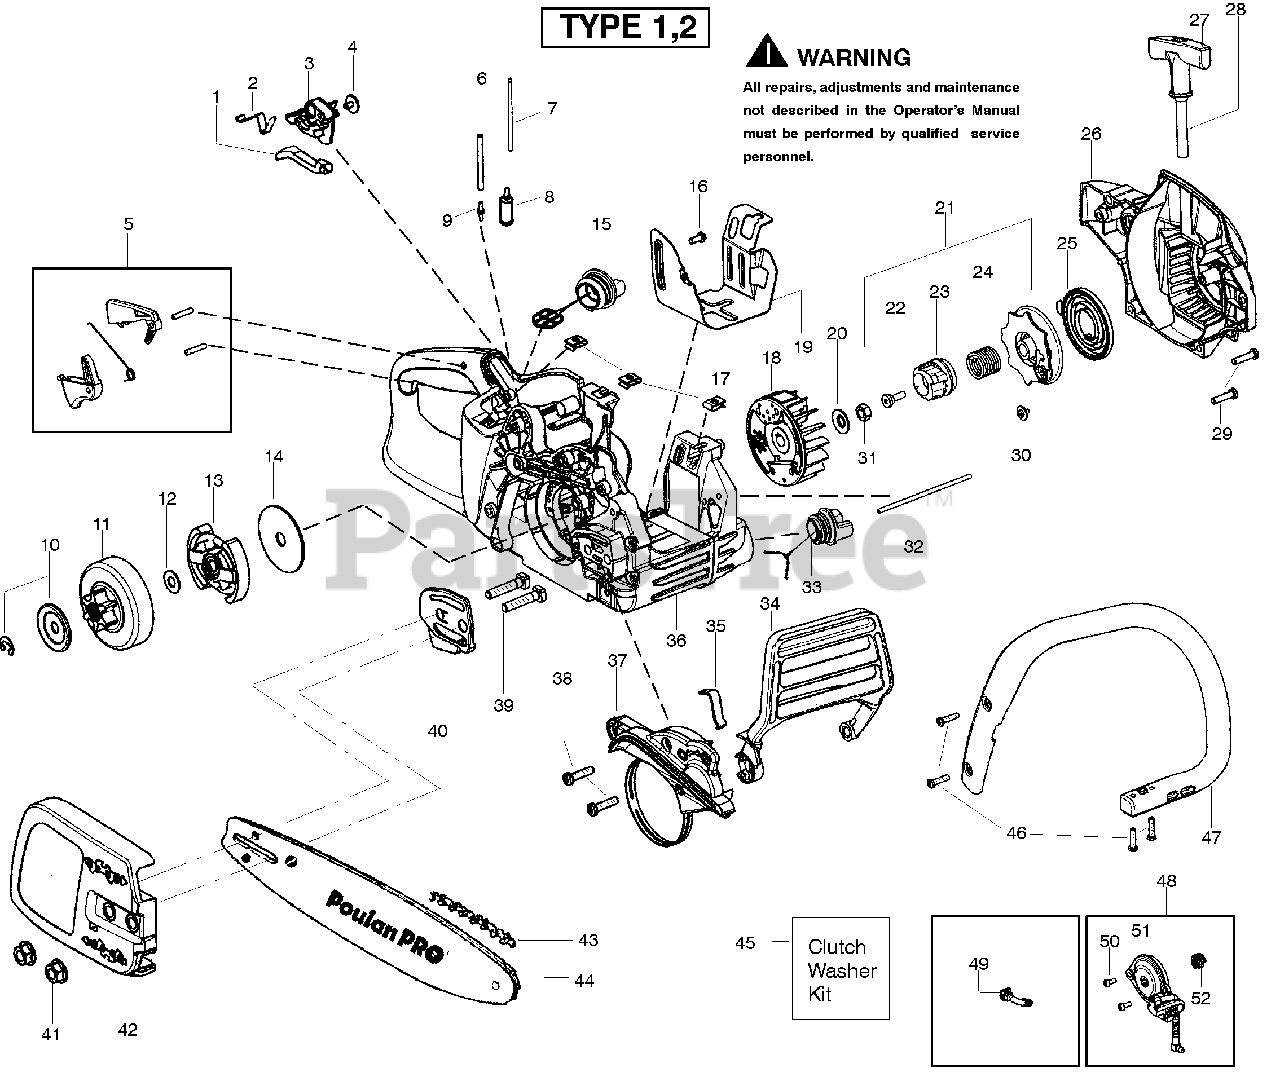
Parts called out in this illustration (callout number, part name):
1	Knob-Choke
2	Spring-Ign. Switch
3	Lever-Ign. Switch
5	Kit-Trigger/Lockout
6	Kit-Fuel Line (Large)
7	Kit-Fuel Line (Small)
8	Assy-Fuel Pick Up
9	Fitting-Fuel line
10	Kit-Clutch Washer
11	Assy-Clutch Drum 3/8"
12	Kit-Clutch Washer
13	Assy-Clutch
14	Washer-Large Clutch
15	Assy-Fuel Cap w/ret
17	Nut-"U" type speed
18	Assy-Flywheel
19	Shield-Heat
20	Washer-Flywheel
21	Kit-EPS Starter Pulley
22	Screw-Shoulder
24	Spring-EPS
25	Spring-Starter
26	Housing-Fan
27	Handle-Starter
28	Kit-Rope
31	Nut-Flywheel
32	Assy-Oil Vent
33	Assy-Oil Cap w/ret.
34	Handguard
35	Spring-Handguard
36	Assy-Chassis
37	Kit-Chainbrake
39	Bolt-Bar
40	Plate-Bar
42	Assy-Clutch Cover
43	Accy-18" Chain
44	Accy-18" Bar
45	Kit-Clutch Washer
47	Handle-Front
48	Kit-Oil Pump
49	Assy-Oil Pick Up
51	Assy-Oil Pump
52	Gear-Worm
